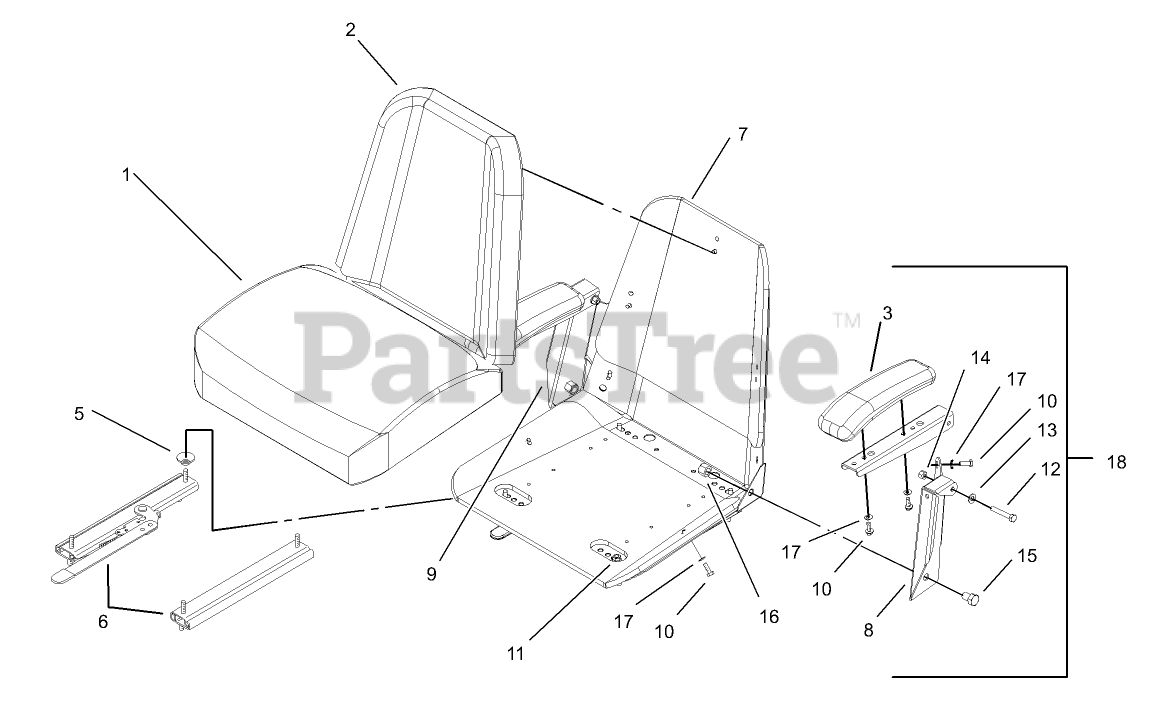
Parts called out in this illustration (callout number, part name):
1	CUSHION-SEAT, BOTTOM
2	CUSHION-SEAT, BACK
5	SPACER-TRACK
6	TRACK-SEAT
7	FRAME-SEAT
10	SCREW-HH
11	NUT-HF
13	WASHER-PLAIN
17	WASHER-FLAT
18	ARMREST KIT
18:1	CUSHION-ARMREST
18:3	SCREW-HH
18:4	CHANNEL-ARMREST
18:5	NUT-HEX, SIDE DEFORM
18:6	Bracket-Armrest, RH
18:7	Bracket-Armrest, LH
18:8	SCREW-HH
18:9	NUT-LOCK, NI
18:10	SCREW-HH
18:11	NUT-HEX
